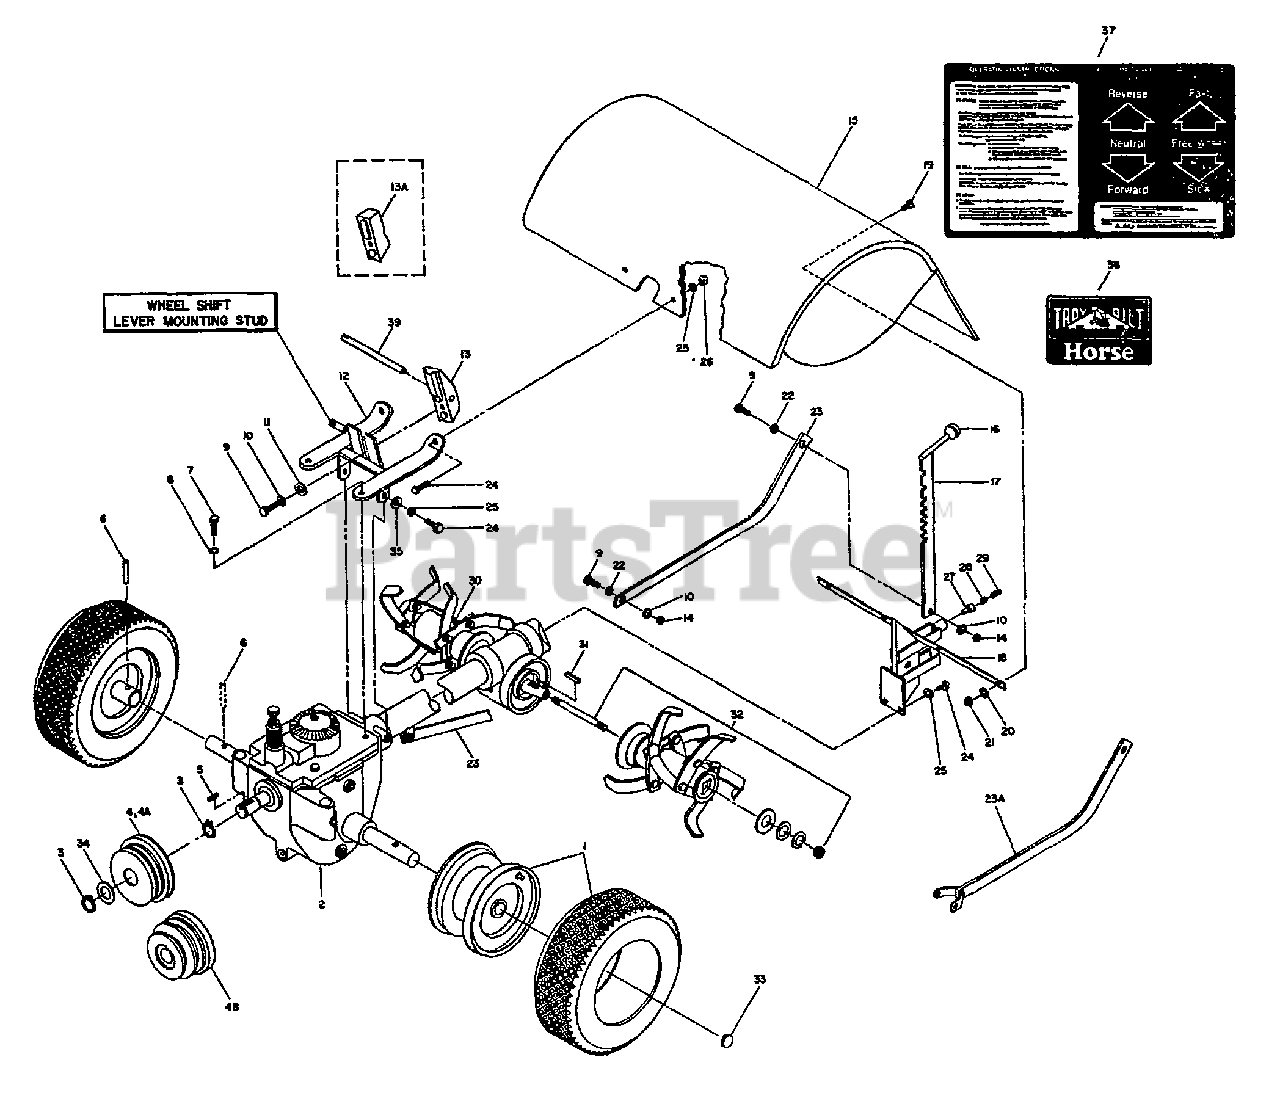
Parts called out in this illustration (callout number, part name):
1	ASSM-STD TIRE
2	CASE
3	RING-RETAIN EXT .707 ID
4	PULLEY-TRANS MACH 2 BELT
4A	KIT-PULLEY CONVERSION
4B	PULLEY-TRANS-MACH
5	KEY-.188 SQX1.0
6	PIN-SPIROL .313 X 1.5
7	BOLT-HH 3/8-16X1.5 FTH ZP
8	WASHER-LK .375 @ DEPL
9	SCR-HH 3/8-16X1.0 G5 ZP
10	WASHER-LK .375 @ DEPL
11	WASHER-1.0X.438X.104 ZP
12	BRKT-FRONT HOOD WELD
13	KIT-ADJ BLOCK 4 SP
13A	BLOCK-BELT ADJUST MACH
14	NUT-HEX 3/8-16 ZP
15	HOOD W/DECALS HI&II
16	KNOB-CONTROL
17	DEPTH REGULATOR W/KNOB
18	KIT-REAR HOOD BRKT
19	SCR-RH 1/4-20 X .75 ZP
20	WASHER-LK .25 ZP
21	NUT-HEX 1/4-20 ZP
22	BUSHING-.5X.375X.3
23	BAR-DRAG PNT RED
23A	ASSM-WELD DRAG BAR PNT
24	SCR-HHC 5/16-18X.75 GR 5 ZP
25	WASHER-LK .312 ZP
26	NUT-HEX 5/16-18 ZP
27	PLUNGER
28	SPRING .406 X 1.25
29	PLUG-PIPE 1/4 NPT
30	BOLO TINE ASSEMBLY, RIGHT
31	KEY-.188 SQX1.0
32	SEE TINE ASSEMBLIES, PAGES 18 & 19
33	CAP-HUB BLK PLASTIC
34	SHIM-1.0X.7656X.062
35	WASHER-FLAT 5/16 SAE
36	SCR-HH 3/8-16X1.25
37	DECAL-HOOD
38	DECAL-HORSE LOGO OPC
39	BAR-ADJUST
